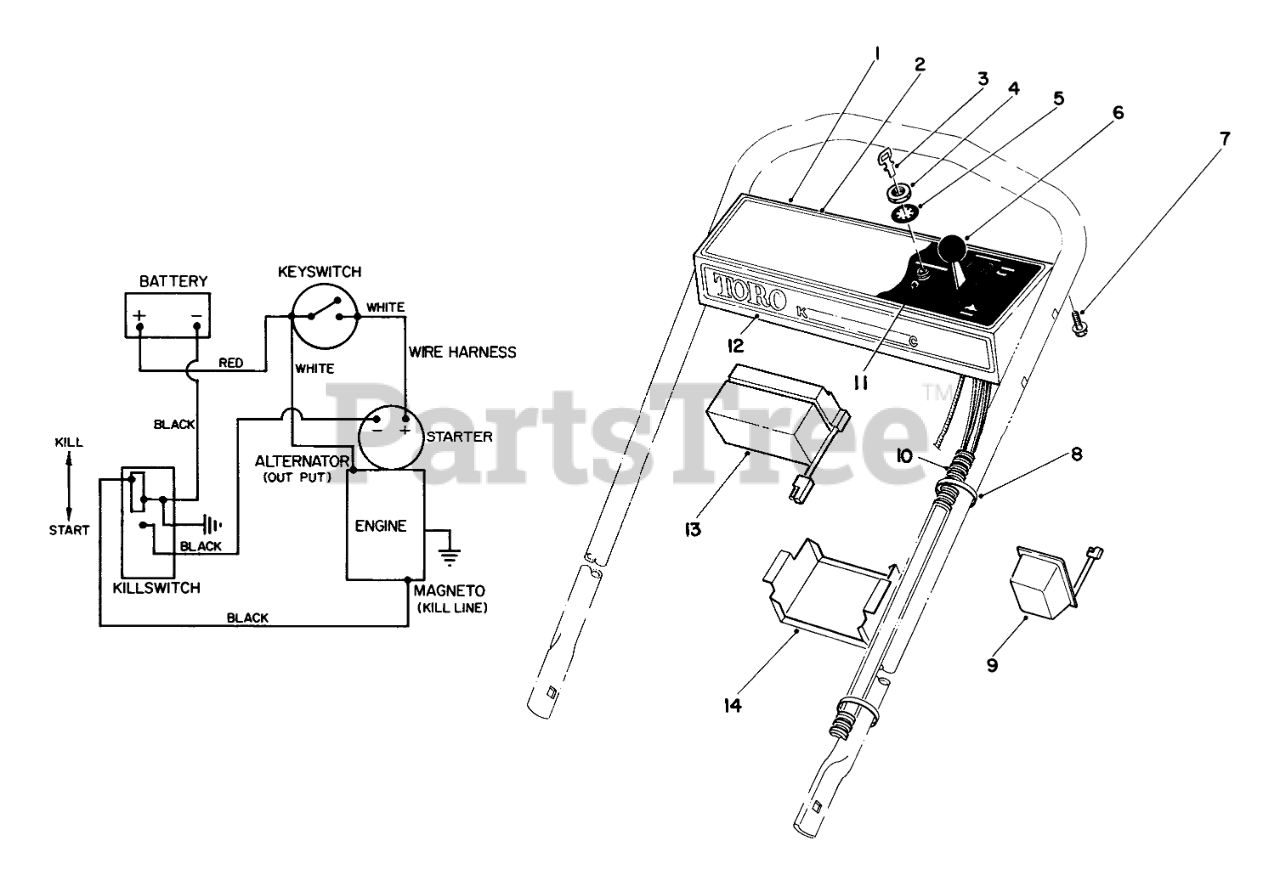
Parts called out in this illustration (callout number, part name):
1	Control Panel (Incl. Ref . #2)
2	Decal-Instructions
3	KEY-IGNITION
4	NUT-HH
5	WASHER-TOOTH, INTERNAL
6	SERVICE THROTTLE CONTRO
7	SCREW-HWHTF
8	TIE-CABLE
9	Charger
10	WIRE HARNESS
11	Switch-Starter (Incl. Ref. #4 & 5)
12	Decal-Toro
13	Battery
14	BATTERY RETAINER
